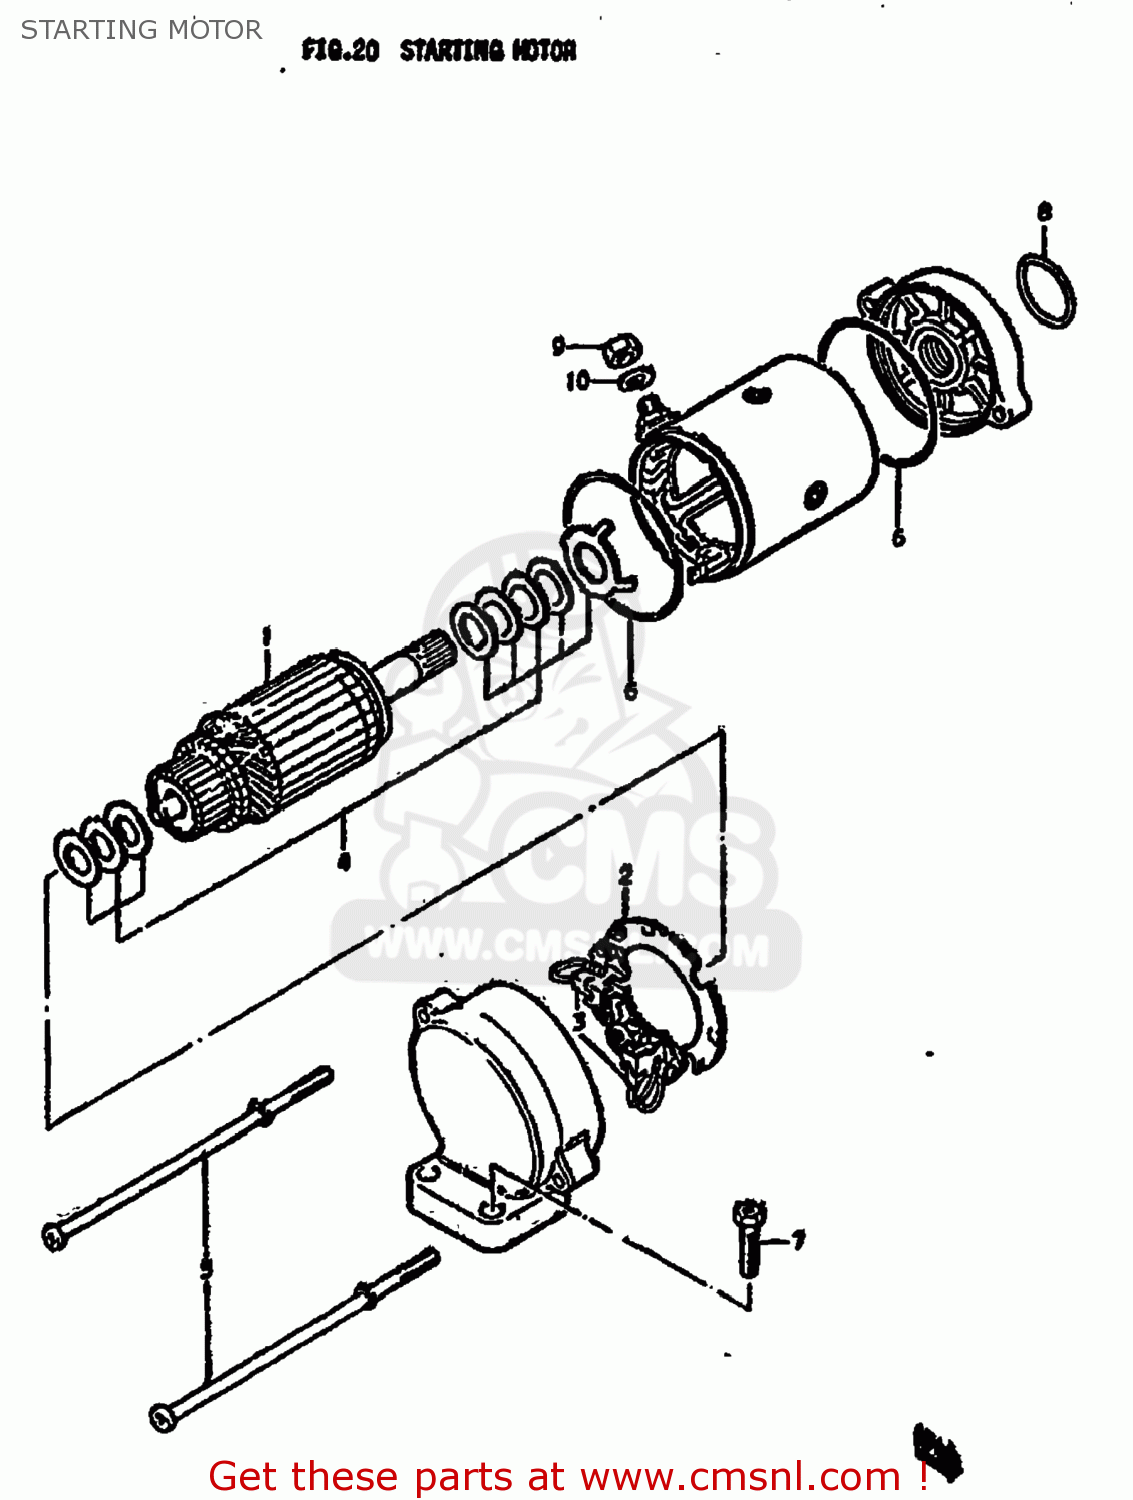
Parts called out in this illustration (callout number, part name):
1	ARMATURE
2	HOLDER ASSY
3	BRUSH SET
4	SHIM SET
5	BOLT,STARTING MOTOR HOUSING
6	O RING
7	SCREW
8	O RING(D:2,ID:24.5)
9	NUT 6MM
10	LOCK WASHER
